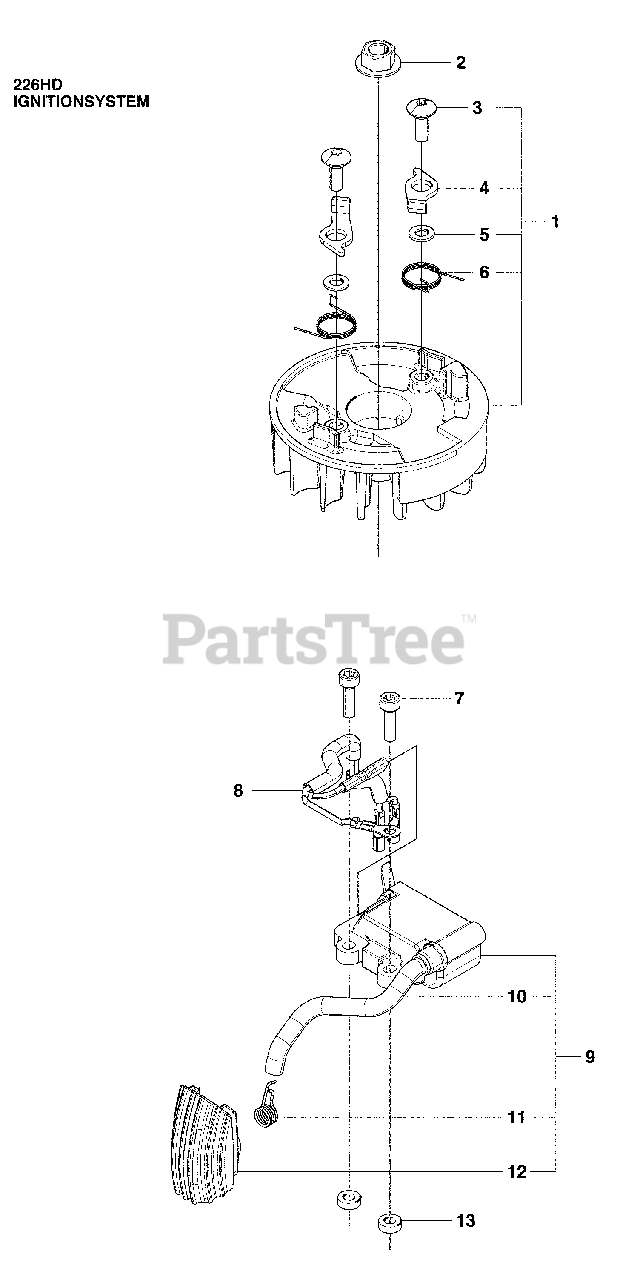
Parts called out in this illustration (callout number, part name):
1	ROTOR ASSY
2	Nut
7	Torx Bolt, M4 X L16
9	Ignition Coil Assembly
13	Spacer
